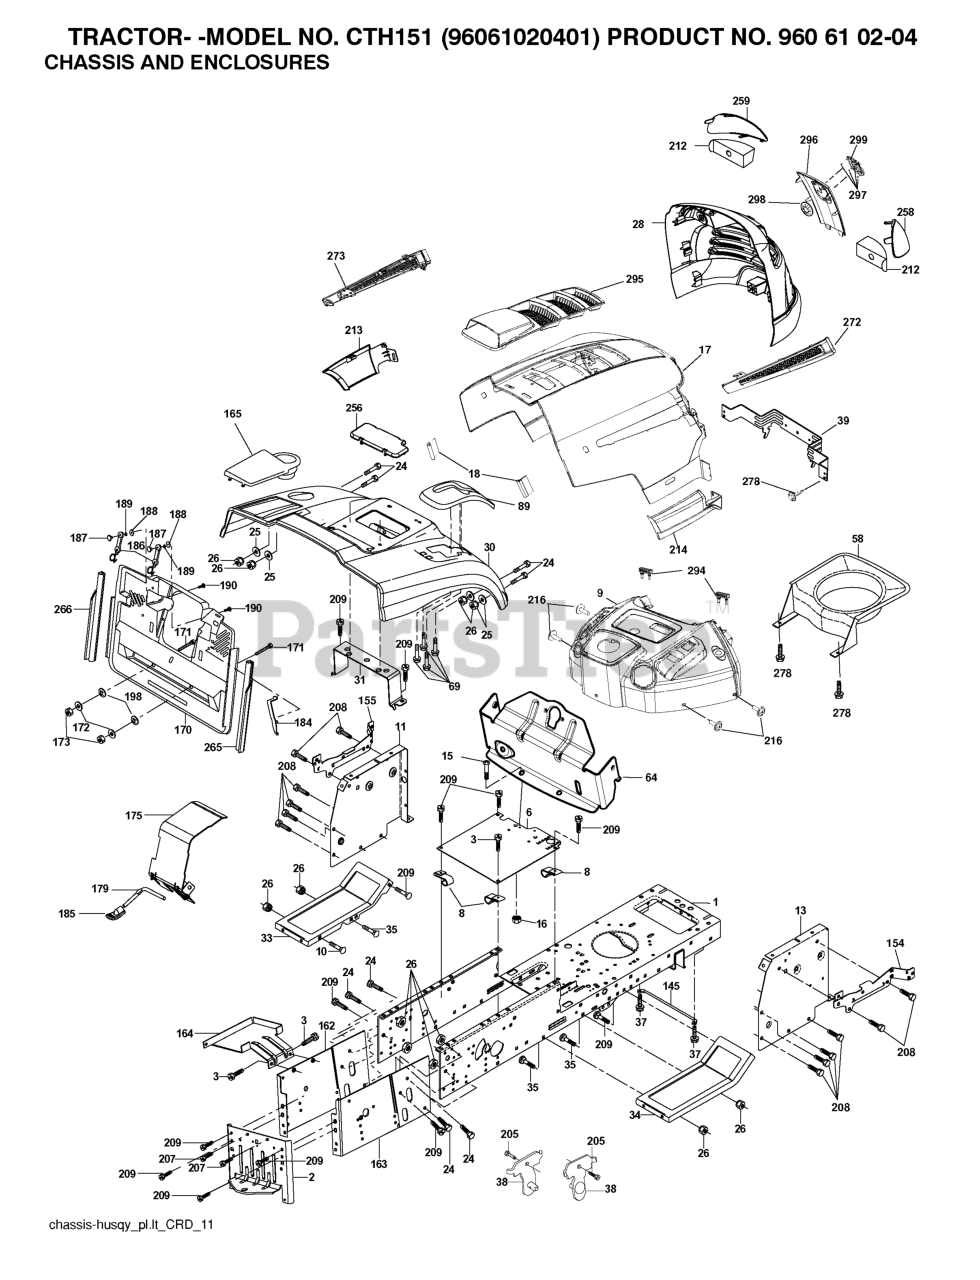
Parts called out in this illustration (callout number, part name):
2	DRAWBAR
3	SCREW 3/8-16X3/4
6	PLATE
8	CLIP,INSULATOR
10	BOLT D
11	PANEL.DASH.LH.LTX
13	PANEL ASM, DASH RH
15	Screw, Machine, Truss Head 5/16-18 UNC x 3/4
16	NUT
17	HOOD
18	BUMPER.HOOD.TEX.HUSQVARNA
24	BOLT
25	WASHER
26	NUT
28	RP GRILLE/LENS ASM.
30	CONSOLE.CRD.AUTO.GRY
31	BRACKET SUPPORT FENDER
33	FOOTREST PNT LH
34	FOOTREST PNT RH
35	BOLT
37	Screw 5/16-18 x 1/2 Hex, Self Tapping 5/16-18 x 1/2
38	BRACKET ASM PIVOT MOWER REAR
39	BRACKET PIVOT
69	SCREW.HI-LO.CONSOLE
89	CONSOLE.CRD.AUTO.GREY.2005
145	ROD.PIVOT.HOOD
162	BRACKET
163	BRACKET EXTEN CHASSIS RH CRD
165	RP.COVER.BATTERY.CRD.GREY
171	BOLT
172	WASHER
175	DOOR TRAP
179	ROD PIVOT FBI
184	BRACKET.ACTUATOR.BAGGER.SRD
186	LATCH ASSY
187	WELDNUT
189	LOCKWASHER #10
190	SCREW
205	SCREW LT
207	SCREW, 5/16-18 X 1/2
208	SCREW 3/8-16X1/2
209	SCREW, 3/8-16X3/4
212	INSERT REFLECTIVE
213	SKIRT SIDE LH
214	SKIRT SIDE RH
216	SCREW HEXWSHR 1/4-20X3/4
256	COVER FENDER CRD
258	LENS.HUSQVARNA LT.RH
259	LENS.HUSQVARNA LT.LH
265	SEALING
266	SEALING
272	VENT SIDE HOOD RH
273	VENT SIDE HOOD LH
278	SCREW
294	BUMPER DASH
295	VENT TOP HOOD
296	TRIM
297	CLIP.RETAINER.TINNER.
298	NUT PUSH M
299	RP LOGO
